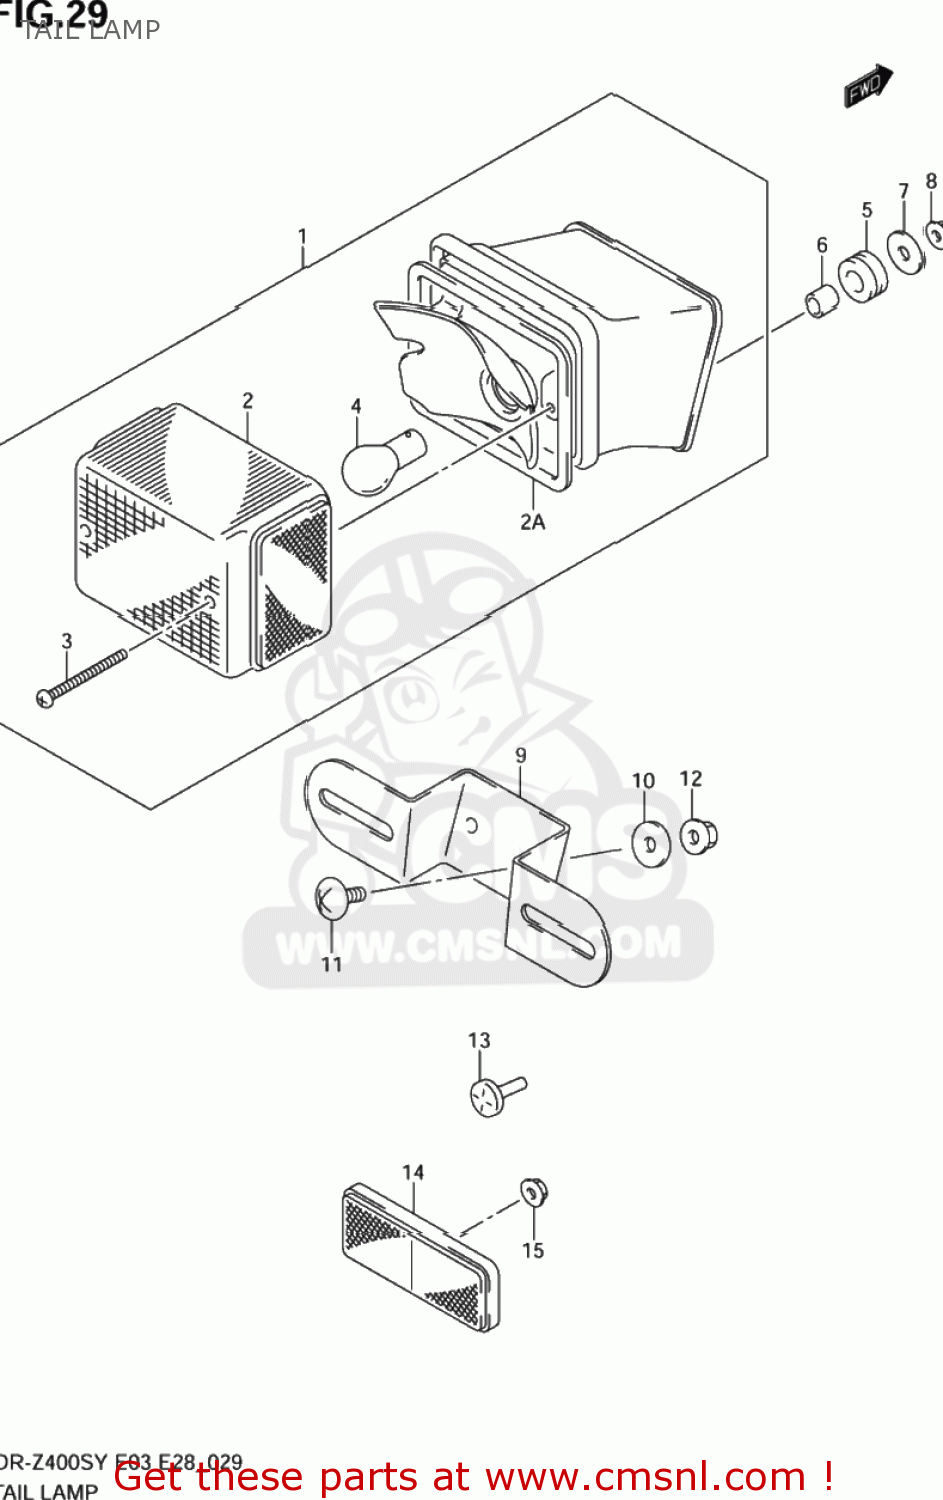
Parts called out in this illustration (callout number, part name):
1	LAMP ASSY,RR COMBINATION
2	LENS
2A	GASKET,LENS (NAS)
3	SCREW(4X45)
4	BULB(12V21/5W)
5	CUSHION
6	SPACER(6.5X10X10)
7	WASHER(6.5X20X1.6)
8	NUT
9	BRACKET,LICENSE PLATE
10	WASHER(6.5X20X1.6)
11	SCREW 6X12
12	NUT
13	CUSHION
14	REFLECTOR ASSEMBLY,REAR
15	NUT
